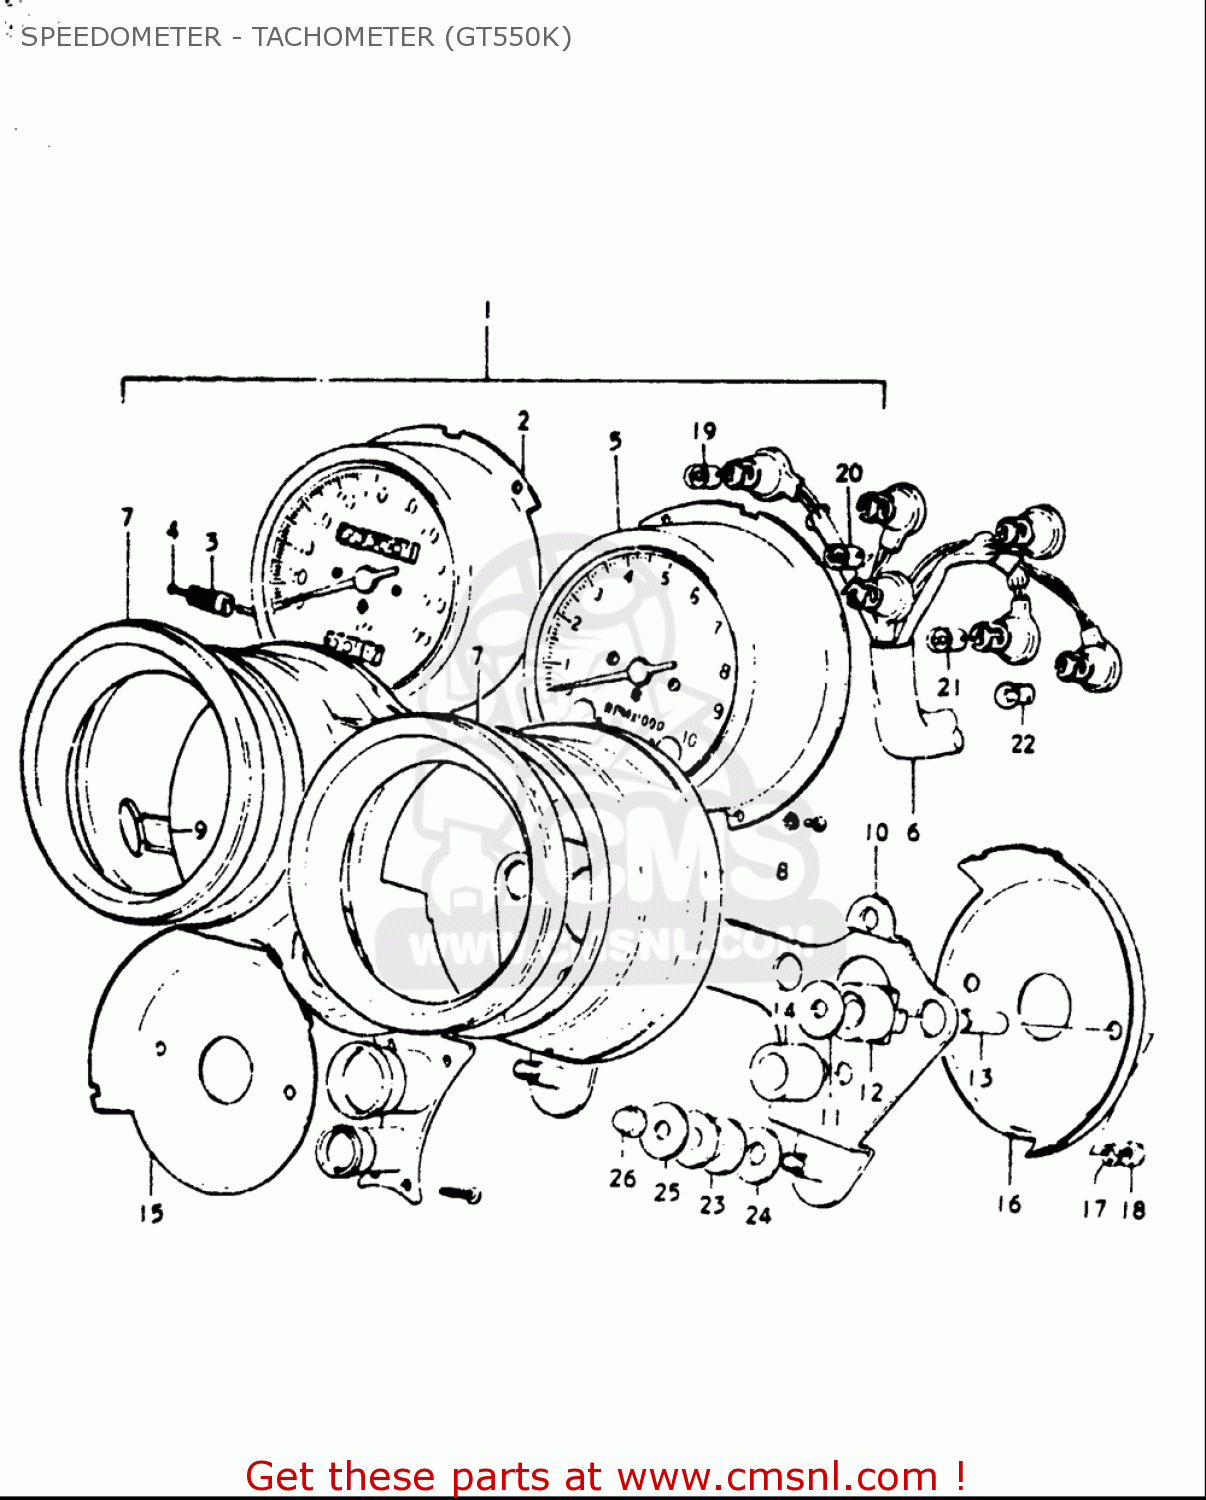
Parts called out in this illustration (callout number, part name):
3	KNOB, TRIP METER
4	SCREW(2X6)
7	VISOR
9	CAP
12	CUSHION,METER NO.1
14	CUSHION,METER
17	WASHER,LOCK
18	NUT
19	BULB(12V3.4W,STANLEY,A72A)
22	BULB(12V1.7W,A71A)
23	CUSHION
24	WASHER(6.5X18X1.6)
25	WASHER
26	NUT
